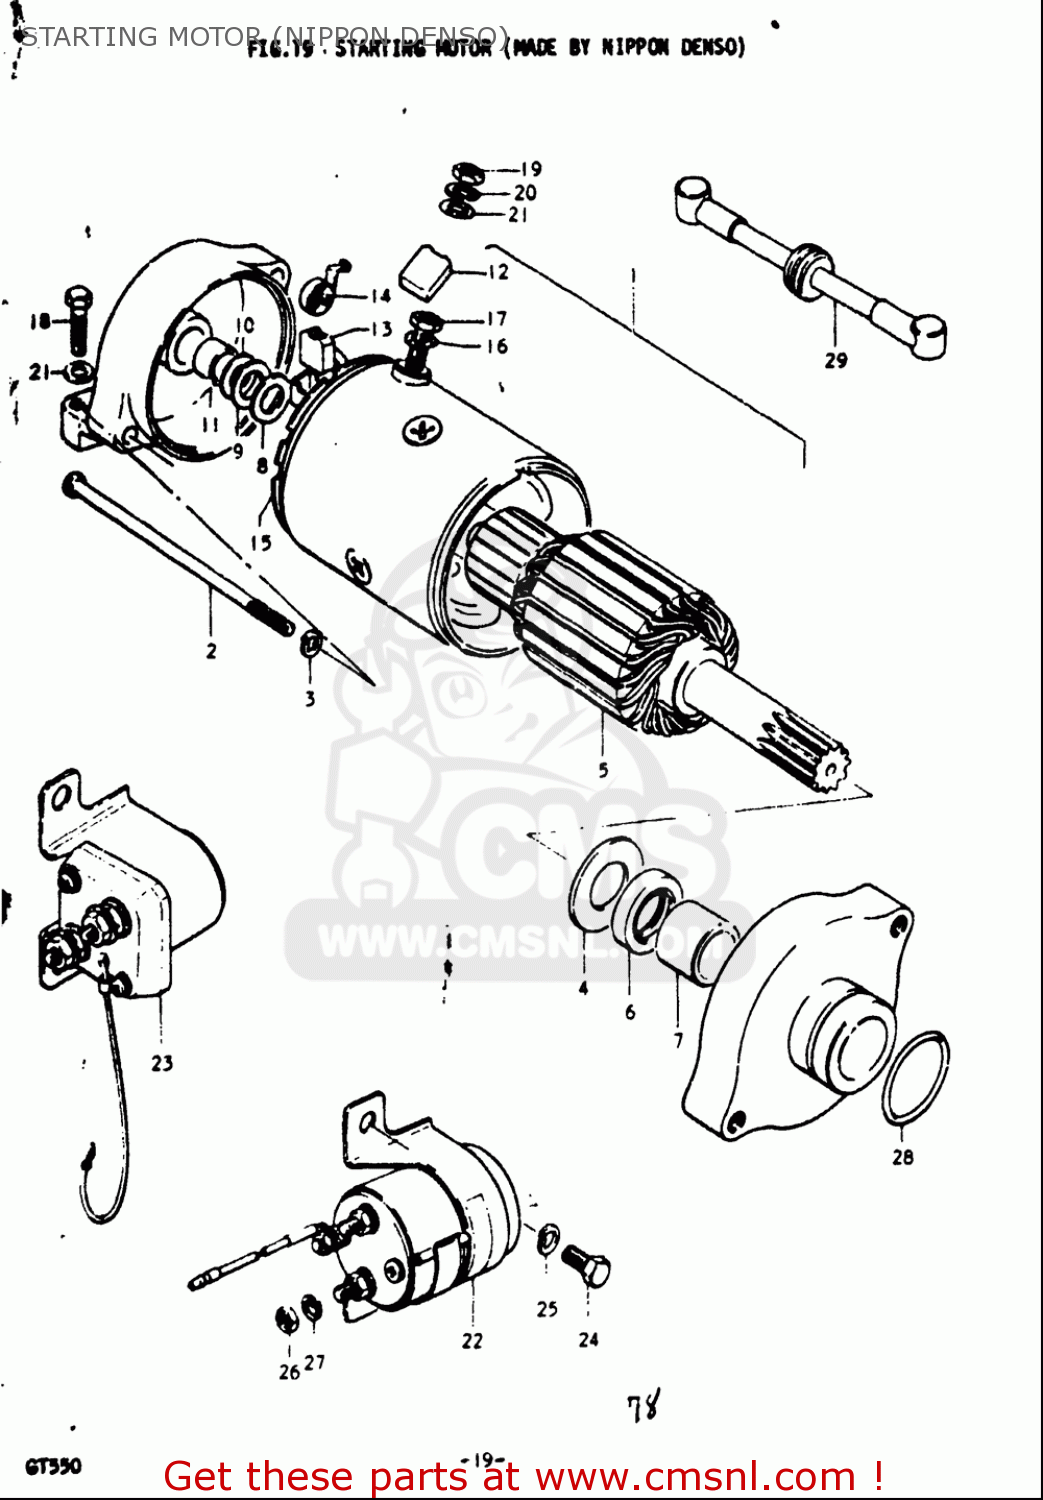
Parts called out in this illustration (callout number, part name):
3	WASHER,LOCK
8	SHIM, (1)
9	SHIM, (2)
10	SHIM, (3)
14	SPRING
15	GASKET
16	WASHER,LOCK
17	NUT
18	BOLT
19	NUT
20	WASHER,LOCK
21	WASHER
22	RELAY ASSY,STARTING MOTOR
23	RELAY ASSY,STARTING MOTOR
24	BOLT
25	WASHER,LOCK
26	NUT
27	WASHER,LOCK
28	O-RING
